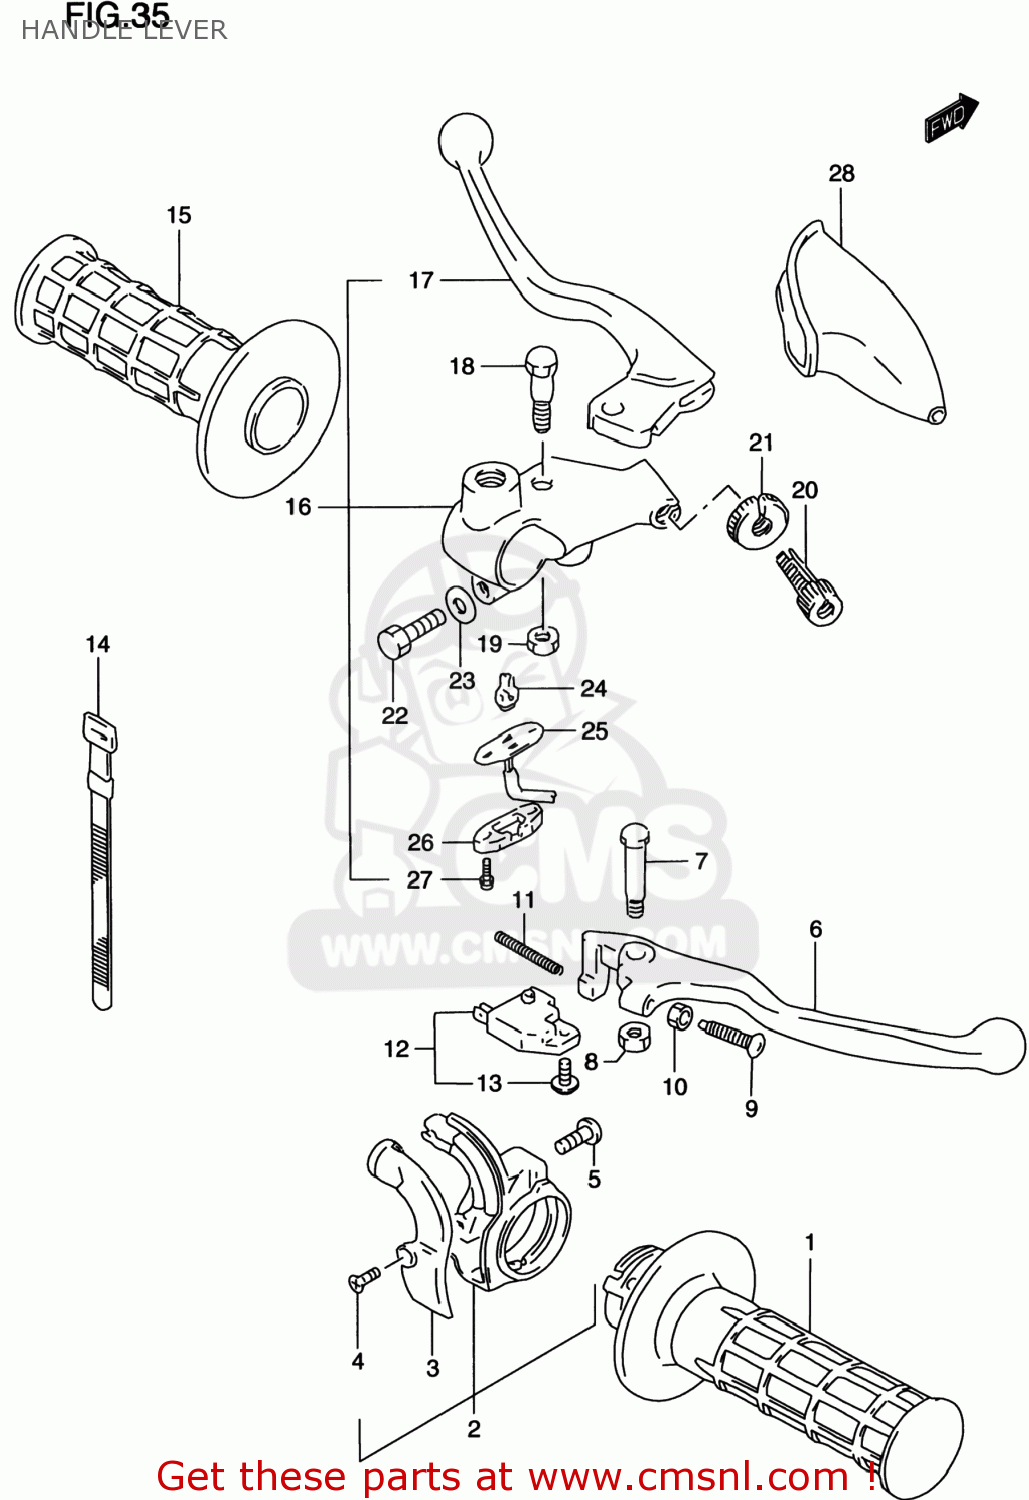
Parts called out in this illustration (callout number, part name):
1	GRIP,THROTTLE
2	CASE ASSEMBLY,THROTTLE
3	COVER,THROTTLE CASE
4	SCREW,UPPER
5	SCREW
6	LEVER,BRAKE
7	BOLT,BRAKE LEVER
8	NUT 6MM
9	BOLT,ADJUST
10	NUT
11	SPRING,RETURN
12	SWITCH ASSEMBLY,STOP
13	SCREW
14	CLAMP(L:120)
15	GRIP,L
16	LEVER ASSEMBLY,CLUTCH
17	LEVER,CLUTCH
18	BOLT,LEVER PIVOT
19	NUT 6MM
20	ADJUSTER,CABLE
21	NUT,LOCK
22	BOLT
23	WASHER
24	CONTACT,SWITCH
25	HARNESS ASSY,WIRE
26	COVER,FR BK TERMINAL BASE
27	SCREW
28	COVER,CLUTCH LEVER
